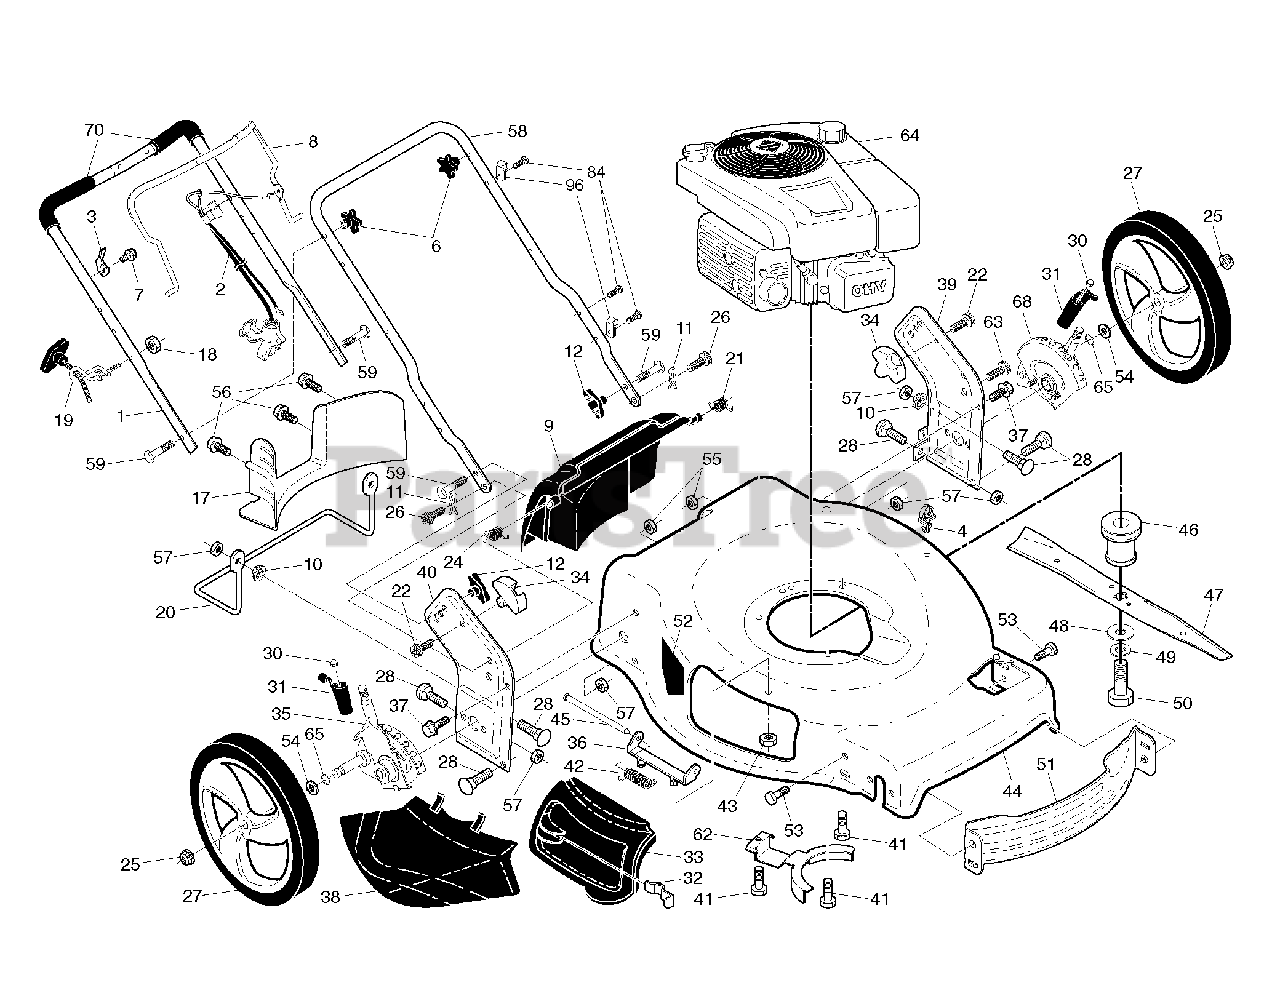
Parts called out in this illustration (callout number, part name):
2	CABLE.ASM
3	BRACKET.UPSTOP.RT
4	PUSH CLIP
6	KNOB.HANDLE.PLASTIC.STAR.BLACK
11	COTTER.HAIRPIN.DOOR/HANDLE.PIV
12	KNOB, DEFLECTOR
18	NUT
19	GUIDE.ROPE.STD.BLK.ZIN
21	SPRING.LH.GRAY
22	SCREW.PAN.HEAD.#10
24	SPRING.RH.GRAY
25	NUT.HEX.FLANGE.3/8-16.LOCKNUT
26	SCREW,DOOR/HANDLE.PIVOT
28	BOLT
32	LATCH.DOOR.ZINC
36	HINGE BRACKET ASSEMBLY
37	BOLT.5/16HEX.WHS.HD
38	DEFLECTOR.CLIPPING.22.BLACK
41	BOLT 3/8-16X1-1/8
42	SPRING.TORSION
43	NUT.HEX.FLANGE.1/4
45	ROD.HINGE.21
46	ADPTER.BLAD.25M.VS.22PLU.STAR
48	WASHER,HARDEN
49	LOCKWASHER
50	SCREW, HEX HD 3/8-24 X 1-3/8
52	DECAL.INTERNATIONL.CUTFINGER
53	BOLT.5/16HEX.WHS.HD
54	WASHER PM
55	NUT.HEX.FLANGE.1/4
56	SCREW.HX.13X.750
57	NUT.FLANGE.5/16
59	BOLT, HANDLE 5/16-18X1.75
62	BRACKET.ENG/BELTKEEPER
65	O-RING..070X.487.NEOPRENE
70	GRIP.HANDLE.FOAM.WIDE.(1 SIDE)
84	FASTENER.PUSH.O.250X0.783
96	CLIP.CABLE.BLK
